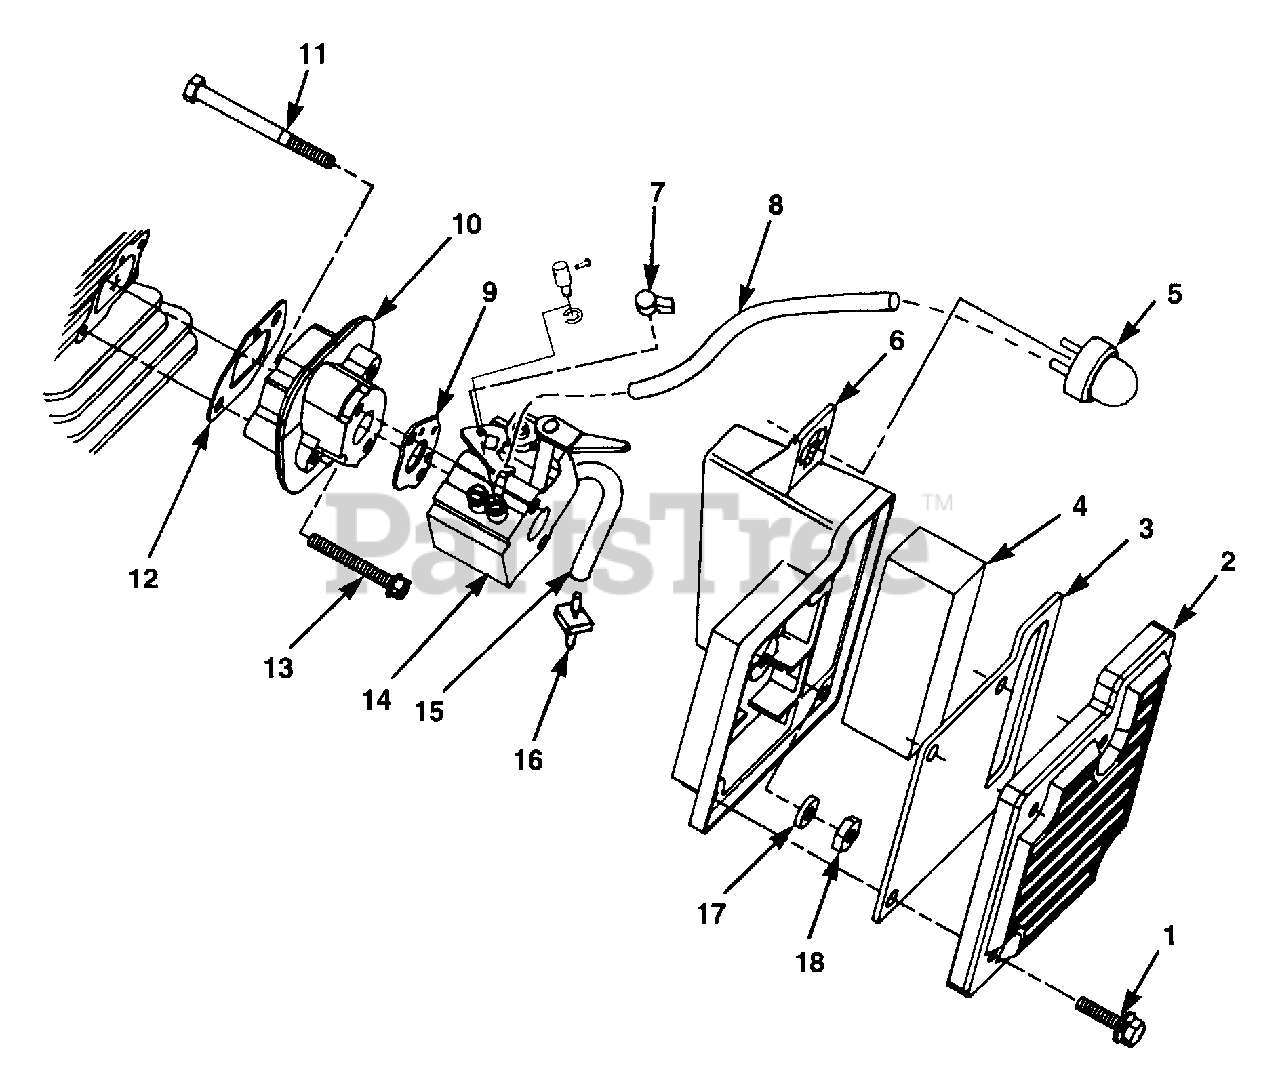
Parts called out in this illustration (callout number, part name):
1	SCREW-Sems Hex Hd (1/4-20 X 7/8")
2	COVER-Air Filter
3	FILTER-Felt Air
4	FILTER-Foam Air
5	BULB-Primer
6	AIR FILTER BOX
7	CAP-Limit
8	TUBING-Rubber
9	GASKET-Carburetor
10	SPACER-Carburetor
11	SCREW-Carburetor Spacer (8-32 X 2")
12	GASKET-Carburetor Spacer
13	SCREW-Sems Hex Hd (8-32 X 1 1/4")
14	CARBURETOR-Zama
15	TUBING-Rubber (5")
16	FITTING-Fuel Inline
17	WASHER-Flat
18	NUT-Hex Machine
